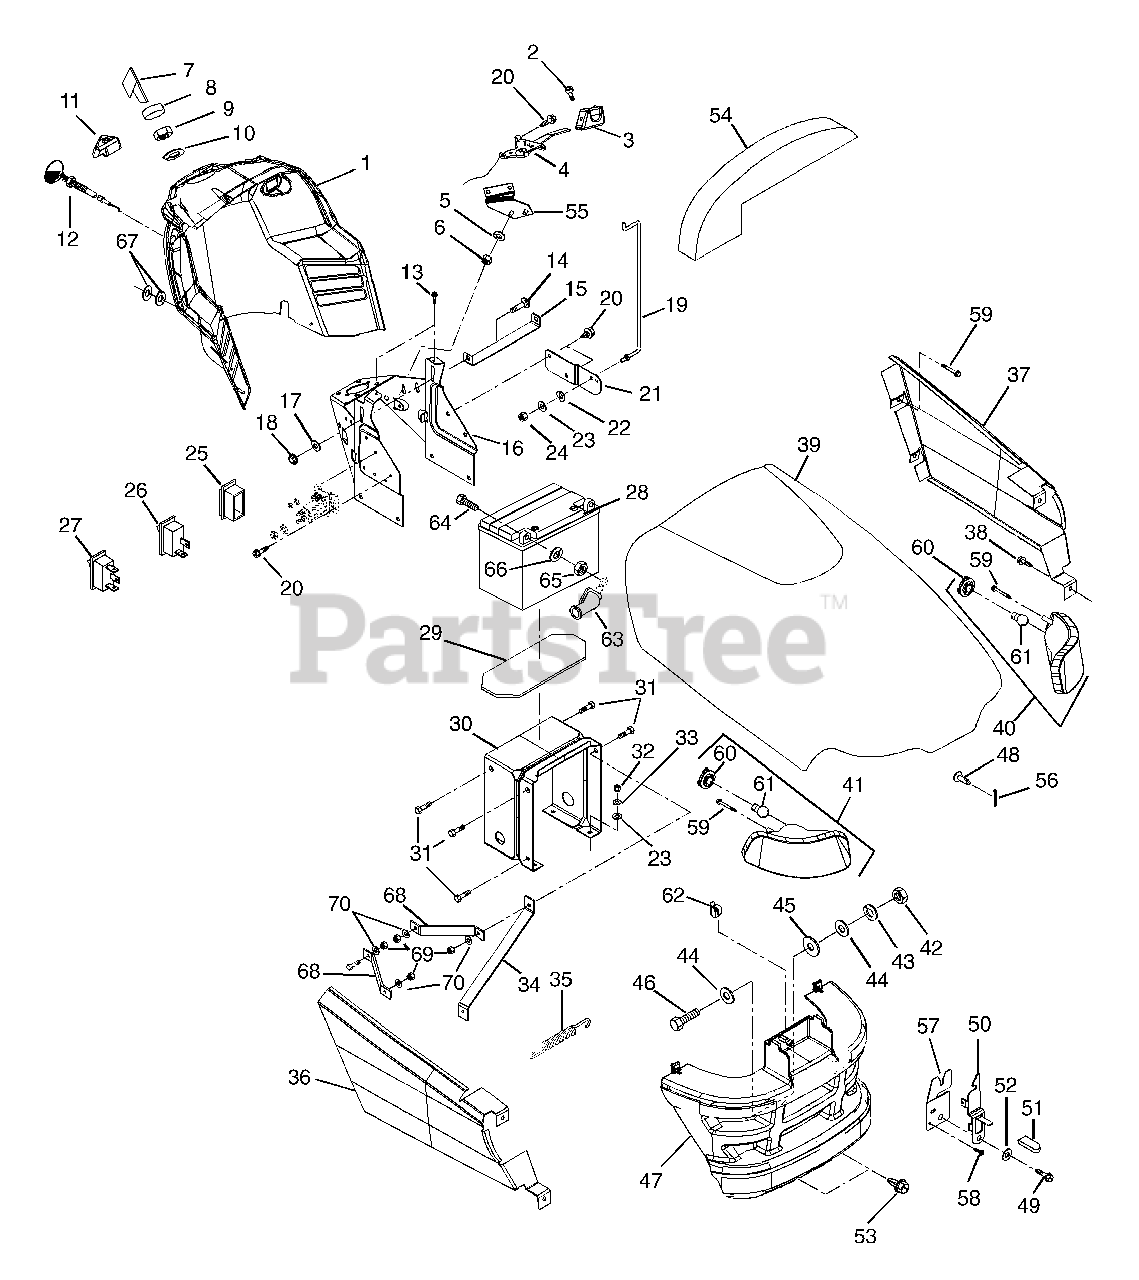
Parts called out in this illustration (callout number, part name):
1	DASH
2	SCR-SET 10-24X.38 UNC-3A
3	KNOB, THROTTLE
4	THROTTLE CONTROL- TEC/B&S
5	WSHR-FL-STL .323X.625X.062 YWZ
6	@NUT-LK-CTR .25-20 YWZC
7	KEY -W/CAP
8	CAP - IGNITION SWITCH
9	NUT- PANEL .562-24 GRECO
10	WSHR-LK-INT .625X.045 YWZC
11	PTO KNOB/ SWITCH ASSY
12	CHOKE CABLE
13	SCR-TAP 10-24X.484 HWH TR
14	@BLT-RDHDSQNK .31-18X.75 G5YZ
15	HOLDDOWN - BATTERY
16	SUPPORT - DASH - TOP
17	WSHR-FL-STL .323X.625X.062 YWZ
18	@NUT-LK-NYL .312-18 YWZC
19	ROD - HOOD PROP
20	@SCR-TAP .25-20X.37 HWH YWZ TR
21	MOUNT - PROP ROD
22	WAVE WASHER .390X.655X.110
23	@WSHR-FL-STL.312X.734X.065 YWZ
24	@NUT-LK-CTR .25-20 YWZC
25	COVER - SWITCH
26	SWITCH - LIGHT
27	SWITCH - CRUISE
28	BATTERY W/TUBE
29	RUBBER PAD
30	SUPPORT DASH BASE
31	@SCR-TAP .31-18X.50 HWH TR YWZ
32	@NUT-HEX .31-18 YWZC
33	WSHR-LK .312X.097 HVY YWZC
35	SG-TENS .035X.45X2.75 WLD 3.5
36	SIDE PANEL- RH
37	SIDE PANEL- LH
38	SCR-TAP 12-16X.500 HI-LOTPHBL
39	HOOD WITH DECALS
40	HEADLIGHT- LH
41	HEADLIGHT- RH
42	@NUT-HEX .31-18 YWZC
43	WSHR-LK .312X.097 HVY YWZC
44	WSHR-FL-STL .328X1.0X.094 YWZC
45	WSHR-FL-NYL .390X1.000X.062
46	@BLT-HEX .31-18X1.00 GR5 YWZC
47	GRILLE
48	PIN, CLEVIS .243/.248X1.50 YWZ
49	SCR-TAP 12-24X.50 HWH TR BLACK
50	HOOD LATCH
51	GRIP .062 X .375 X 1.000 RE
52	WSHR-FL-STL .281X1.250X.048 BL
53	SCR-TAP .312-18X.50 HWH TR BL
54	BAFFLE- HOOD
55	BRACE-THROTTLE CONTROL
56	@PIN-CTR .09X.75 EXTPRSQCT YWZ
57	LOCATOR- HOOD
58	SCR-TAP 10-12X.50 CRPH PL A BL
59	SCR-TAP 10-24X.75 HWH TR YWZC
60	LAMP SOCKET
61	HEADLIGHT BULB, 1156
62	CLIP-HARNESS TINNERMAN
63	INSULATOR
64	@BLT-HEX .25-20X.75 GR5 YWZC
65	WSHR-LK .250X.077 HVY YWZC
66	@NUT-HEX .25-20 YWZC
67	WSHR-FL-STL .219X.500X.049BLZC
68	BRACKET-STEERING ASSEMBLY
69	@NUT-LK-NYL .312-18 YWZC
70	@WSHR-FL-STL.344X.688X.065YWZC
